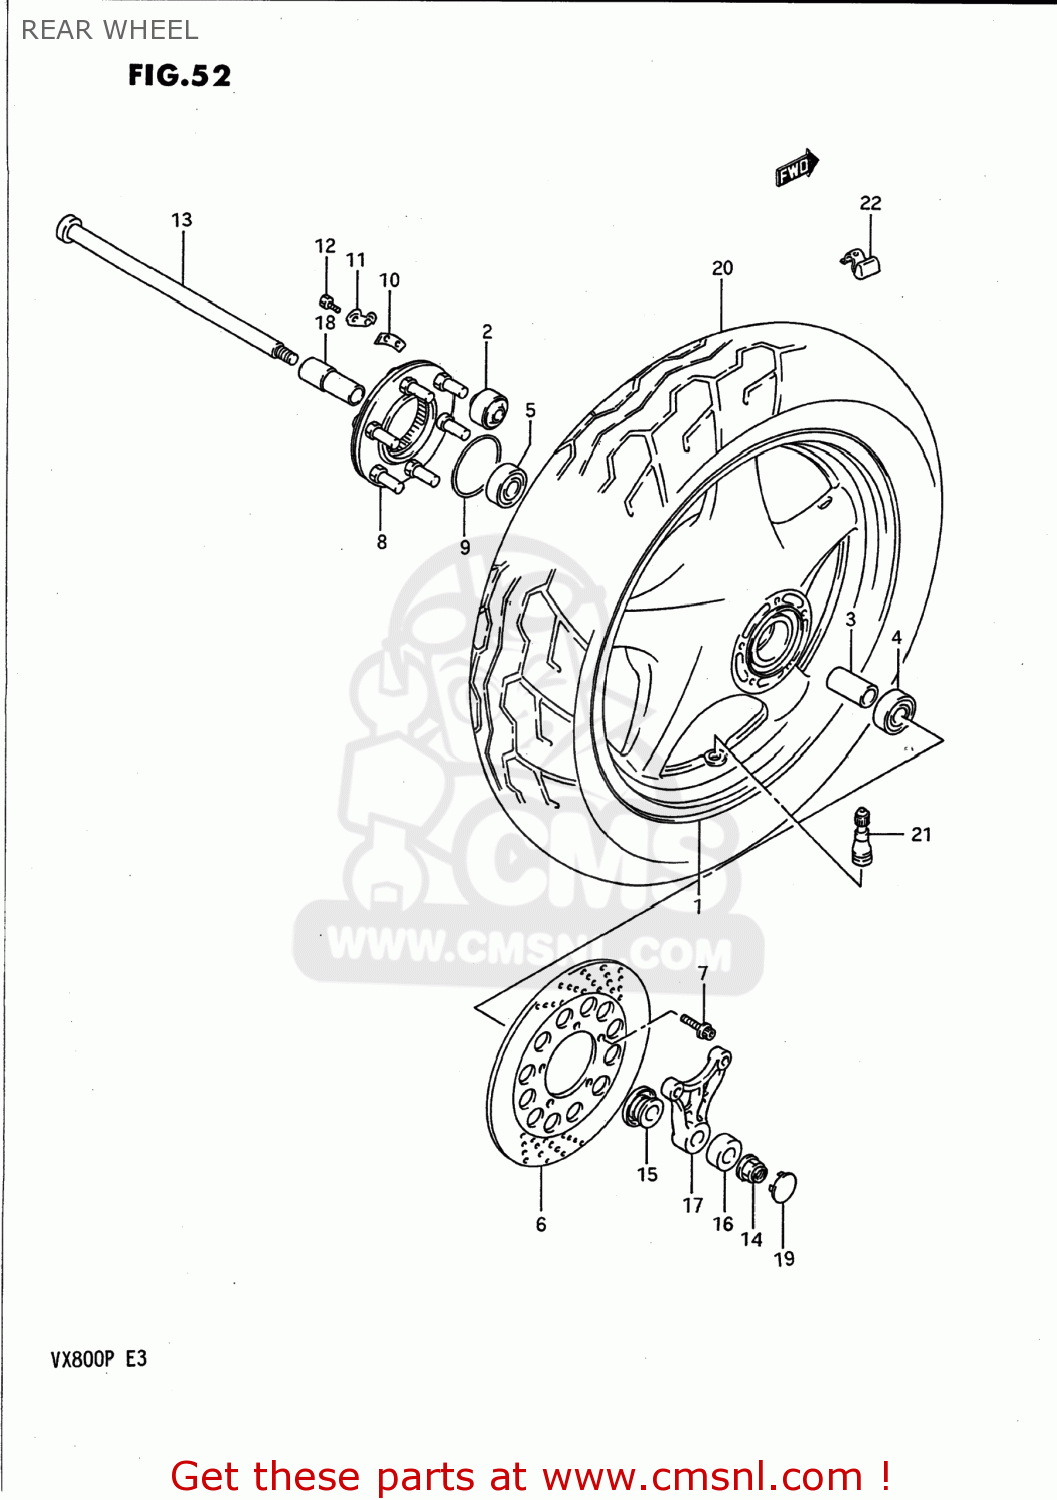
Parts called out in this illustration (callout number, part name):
1	WHEEL SET,REAR (17XMT3)
2	BUSH
3	SPACER,REAR HUB BEARING
4	BEARING
5	BEARING
6	DISC,RR BRAKE
7	BOLT, REAR
8	JOINT ASSEMBLY,REAR HUB DRUM
9	O RING(D:2.1,ID:65)
10	WASHER,THRUST(T:1.6)
11	WASHER
12	BOLT(6X16)
13	AXLE,REAR
14	NUT
15	SPACER,REAR AXLE,RIGHT
16	SPACER,RR AXLE,R
17	BRACKET,RR,CALIPER
18	SPACER,RR AXLE,L
19	CAP,RR AXLE,R
20	TIRE
21	VALVE ASSY,WHEEL RIM(TR412)
22	BALANCER,WHEEL
